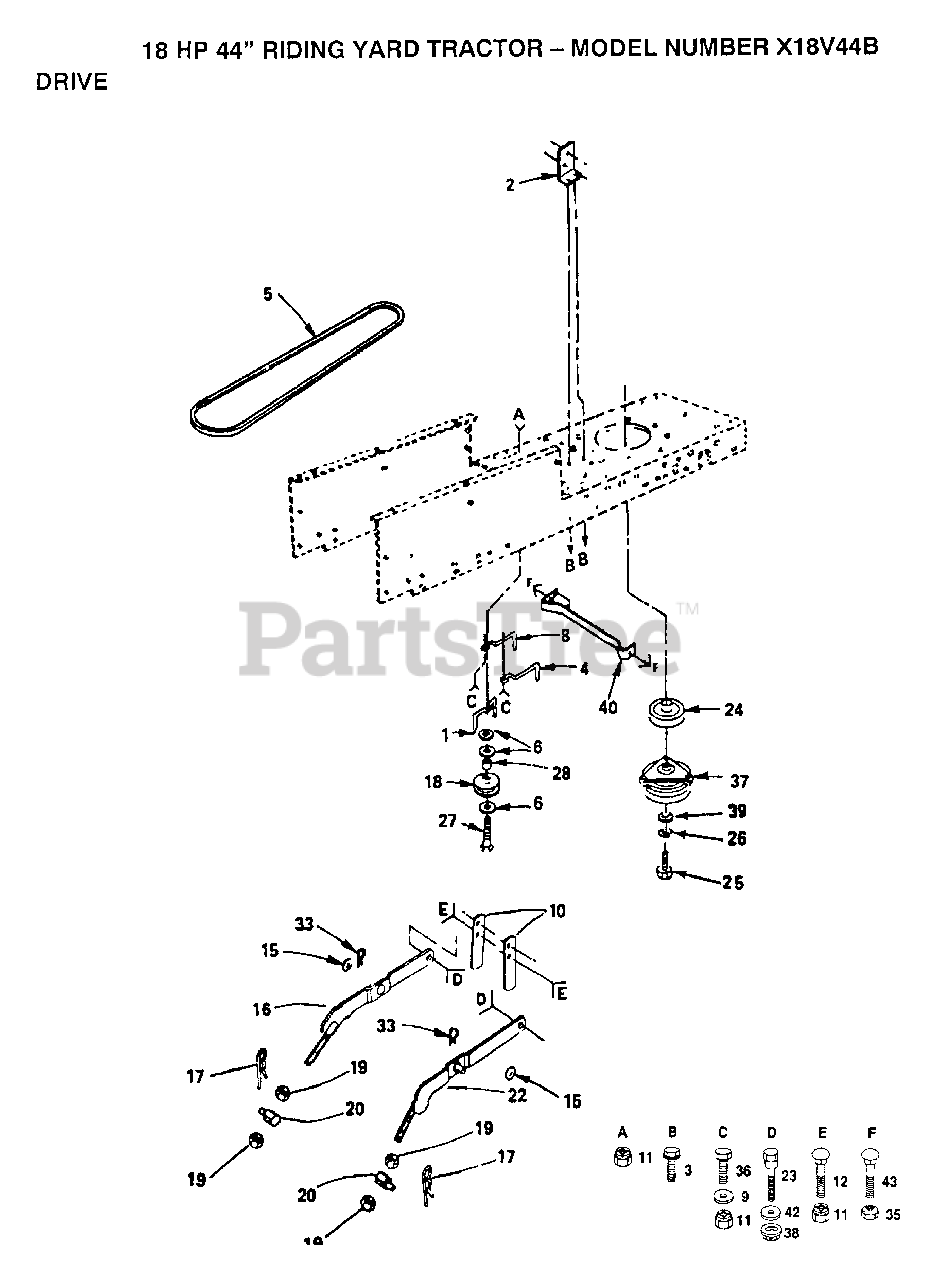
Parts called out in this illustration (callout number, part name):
1	BELT KEEPER LT
2	BRACKET LT
3	SCREW
4	"KEEPER,BLT ENG LT"
5	BELT.GRDRV.94.75
6	WASHER
8	KEEPER BELT ENGLH
9	WASHER
10	UPSTOP
16	LH SUSP ARM ASM
17	SPRING H
18	PULLEY.IDLER.FLAT
19	NUT
22	RH SUSP ARM ASM
23	"BOLT, SHOULDER LT"
26	LOCKWASHER
27	BOLT
28	SPACER T
33	SPRING.RETAINER
36	BOLT
37	CLUTCH, ELECTRIC
38	NUT SPECIAL T
39	WASHER
42	WASHER T
43	BOLT
